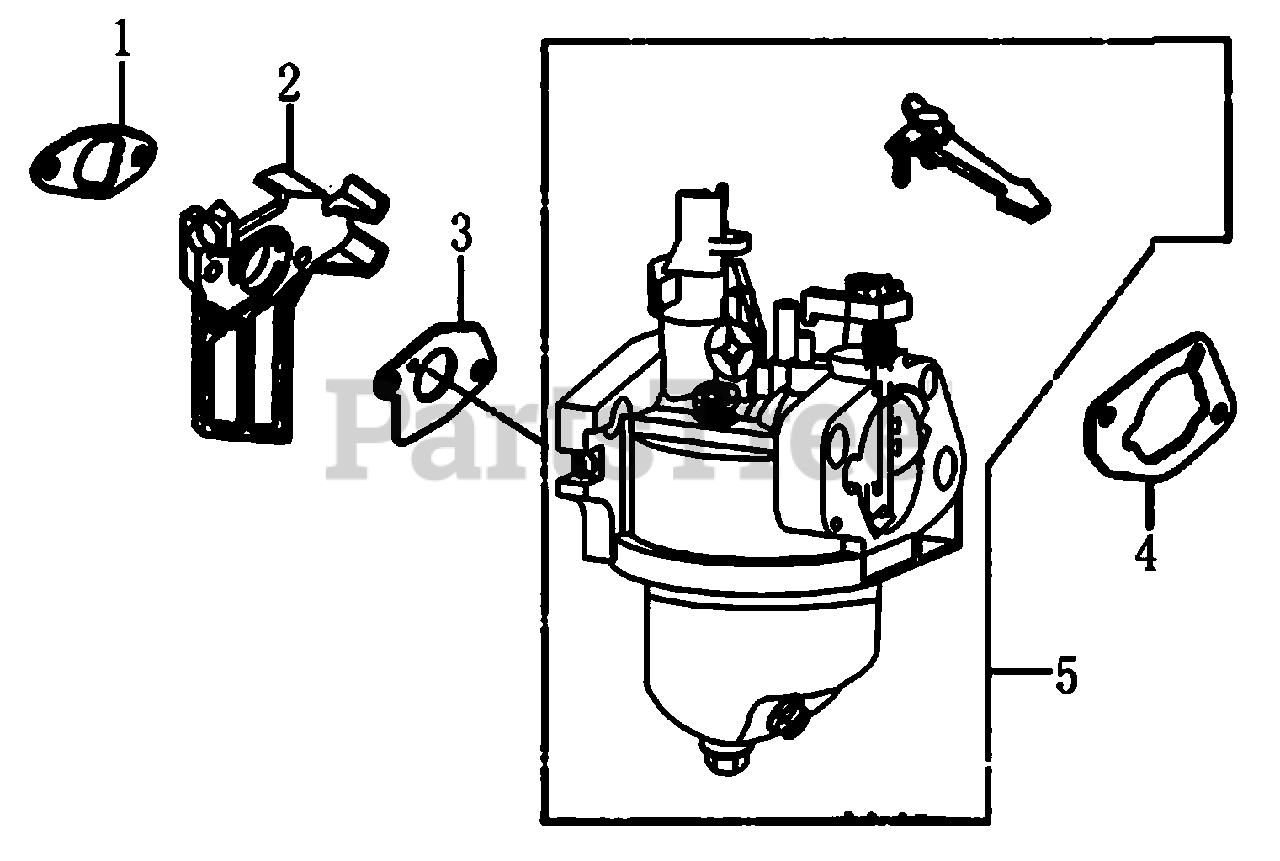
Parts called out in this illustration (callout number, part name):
1	GASKET, INSULATOR
2	INSULATOR , CARBURETOR
3	GASKET, CARBURETOR
4	GASKET, CARBURETOR
5	CARBURETOR
